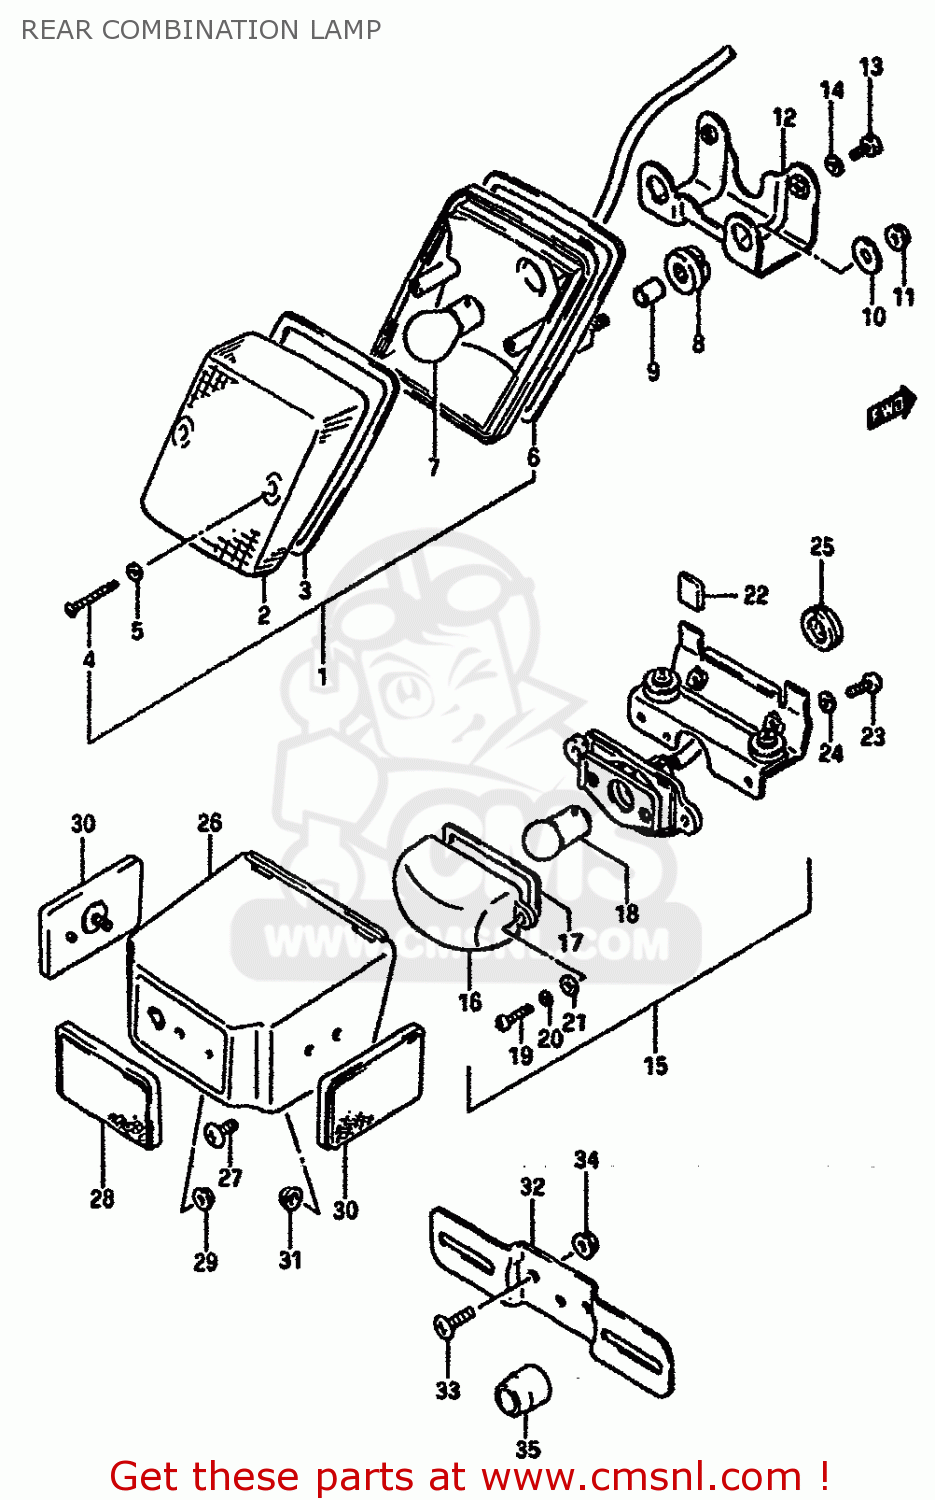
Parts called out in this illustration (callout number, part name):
1	LAMP ASSY,REAR COMBINATION
2	LENS,RR COMBI
3	GASKET,REAR COMBINATION LAMP
4	SCREW TAPP.
5	GASKET (NAS)
6	GASKET
7	BULB(12V21/5W)
8	CUSHION
9	SPACER (6.8X10X10)
10	WASHER (6.5X20X1.2)
11	NUT
12	BRACKET,REAR COMBINATION LAMP
13	BOLT
14	WASHER,LOCK
15	LAMP ASSY, LICENSE
16	LENS,LICENSE LAMP
17	GASKET,LICESE LAMP (NAS)
18	BULB
19	SCREW
20	WASHER,LOCK 4M
21	WASHER 4MM
22	CAP,LICENSE
23	SCREW
24	WASHER,LOCK
25	GROMMET
26	COVER,LICENSE LAMP
27	SCREW
28	RR ASSY,RR
29	NUT
30	REFLEX REFLECTOR, REAR SIDE
31	NUT
32	BRACKET, LICENSE PLATE
33	SCREW
34	NUT
35	CUSHION
